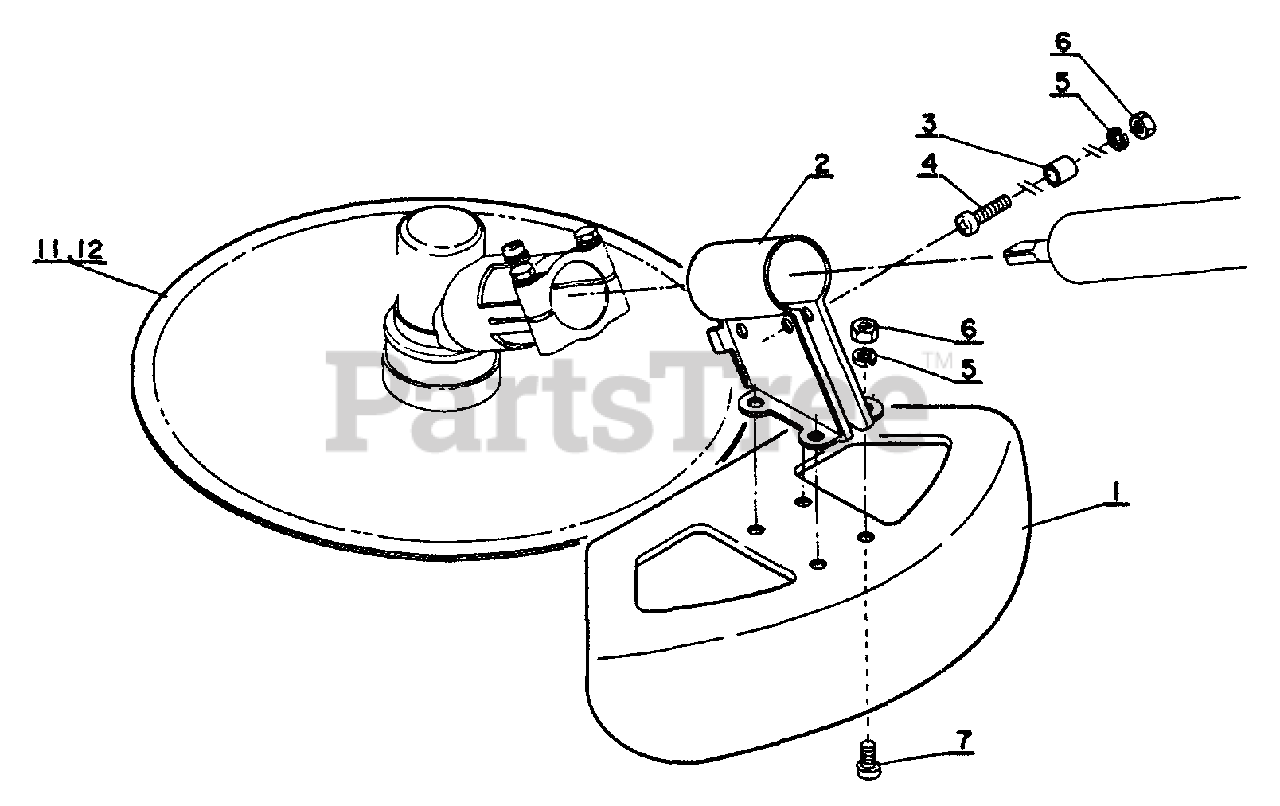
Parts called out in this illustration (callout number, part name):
1	SHIELD, DEBRIS
2	BRACKET, SHIELD
4	SCREW - 5X18
5	LOCKWASHER - 5
7	SCREW - 5X8
11	BLADE - 10" (25cm)
12	BLADE - 8 TOOTH
